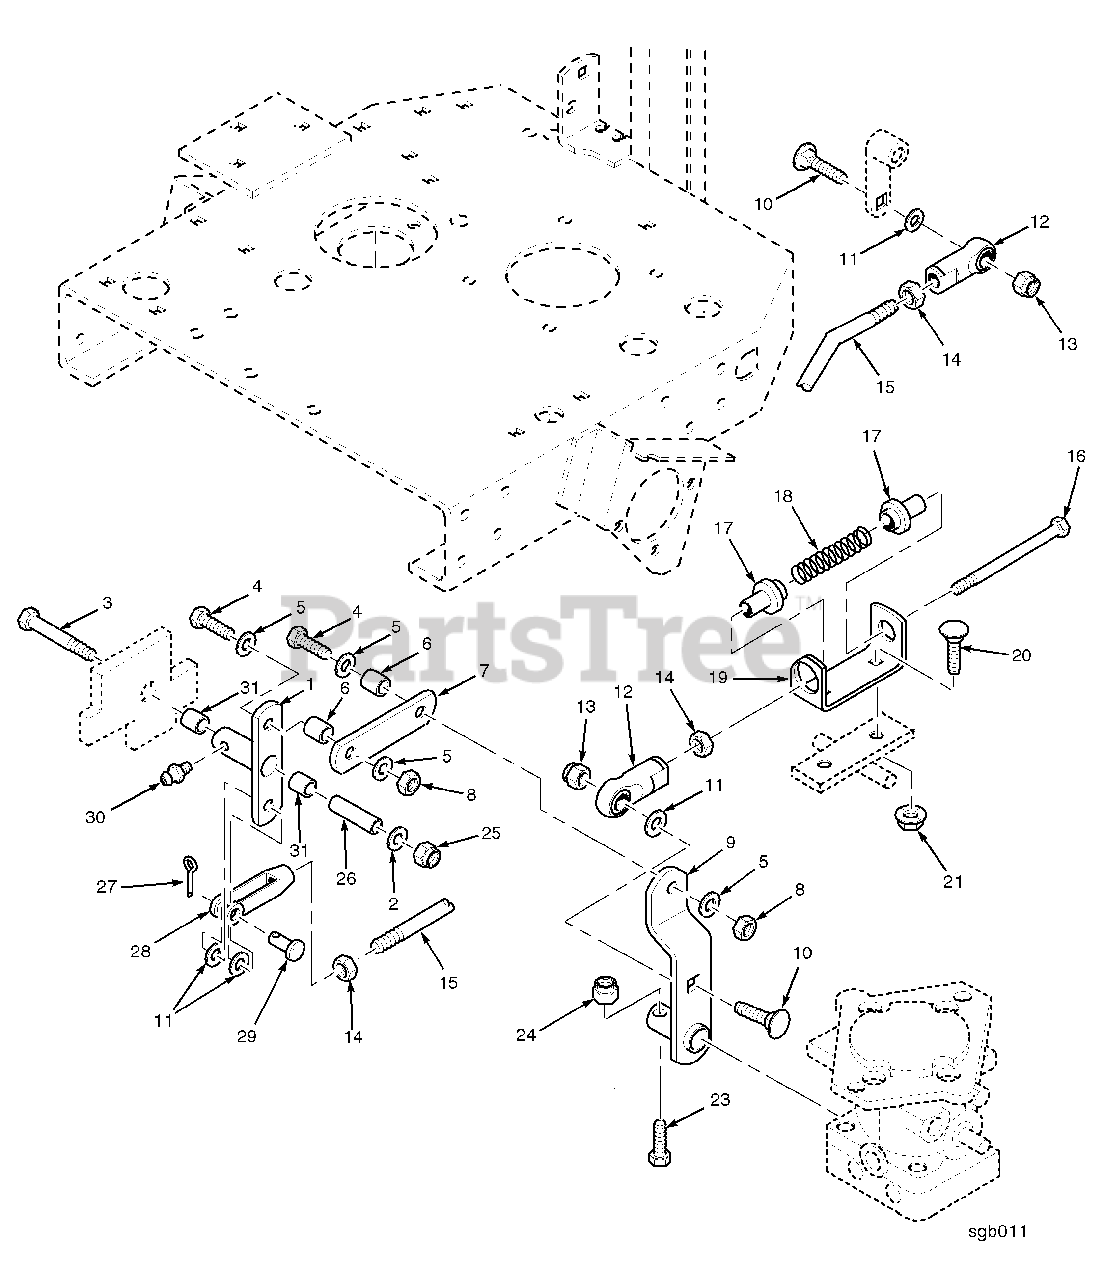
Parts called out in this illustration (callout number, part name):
1	Control Linkage, Bellcrank
2	Flatwasher, 5/16
3	Bolt, Hex Head 5/16-18 x 2-3/4"
4	Bolt, Hex Head 3/8-16 x 1"
5	Flatwasher, 3/8
6	Sleeve, Pump Control Link
7	Link, Speed Control
8	Hex Locknut, 3/8-16
9	Control Arm, Pump
10	Carrage Bolt, RHSSN 3/8-16 x 1-1/2"
11	Flatwasher, 3/8
12	Rod End, RH Female THD 3/8-24
13	Hex Locknut, Elastic Stop 3/8-16
14	Hex Nut, 3/8-24
15	Control Rod
16	Bolt Hex Head, 3/8-24 x 6-3/4"
17	Bushing, Spring Keeper
18	Spring, Neutral Return
19	Retainer, Neutral Spring
20	Carrage Bolt, 5/16-18 x 1"
21	Serr. Fl. Hex Nut 5/16-18
22	Number Not Used
23	Bolt, Hex Head 1/4-20 x 1-1/4"
24	Hex Locknut, Elastic Stop 1/4-20
25	Hex Locknut, Elastic Stop 5/16-18
26	Sleeve, Control Arm
27	Cotter Pin, 3/32 x .75"
28	Clevis, Pump Control
29	Pin, Clevis 3/8"
30	Grease Fitting, 1/4-28 Self Tap
31	Bushing, Bronze
